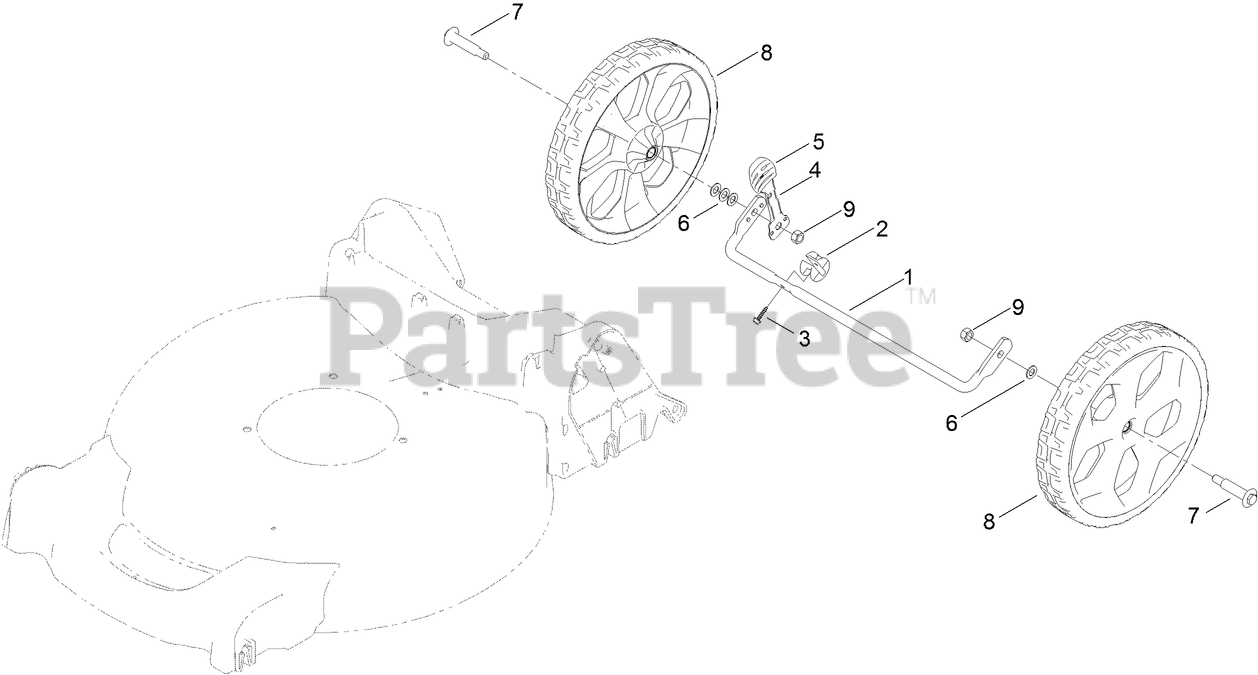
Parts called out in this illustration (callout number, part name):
2	STOP-AXLE
3	SCREW-HWH
4	ARM-SPRING, REAR
5	KNOB-LEVER, HOC
7	BOLT-SHOULDER
8	11 INCH WHEEL ASM
9	LOCKNUT
